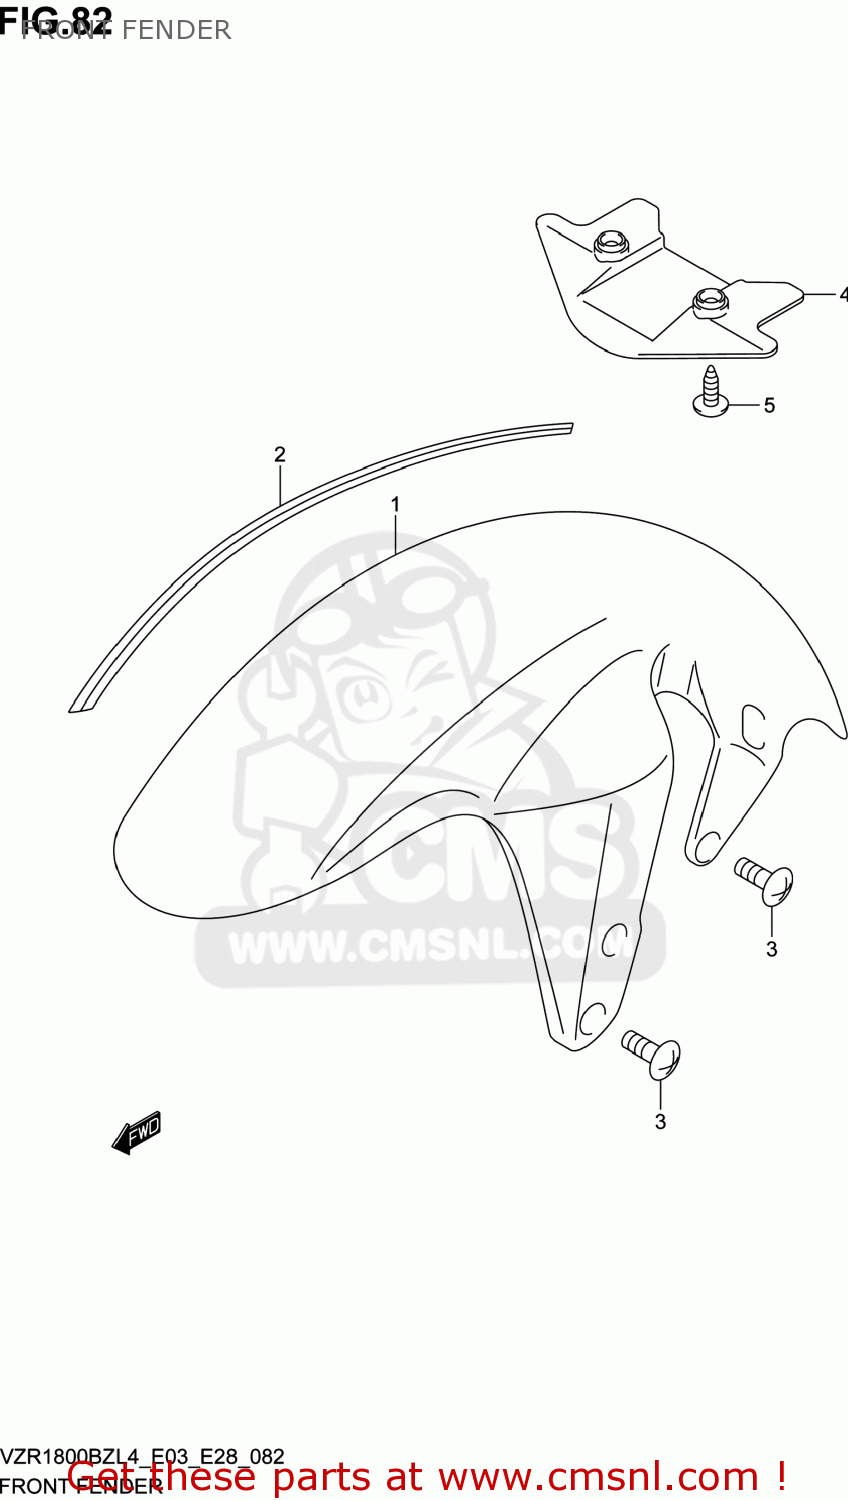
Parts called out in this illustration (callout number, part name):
1	FENDER,FRONT
2	TAPE SET,FR FENDER
3	SCREW(6X16)
4	FENDER,FR UPPER
5	BOLT(6X16.5)
